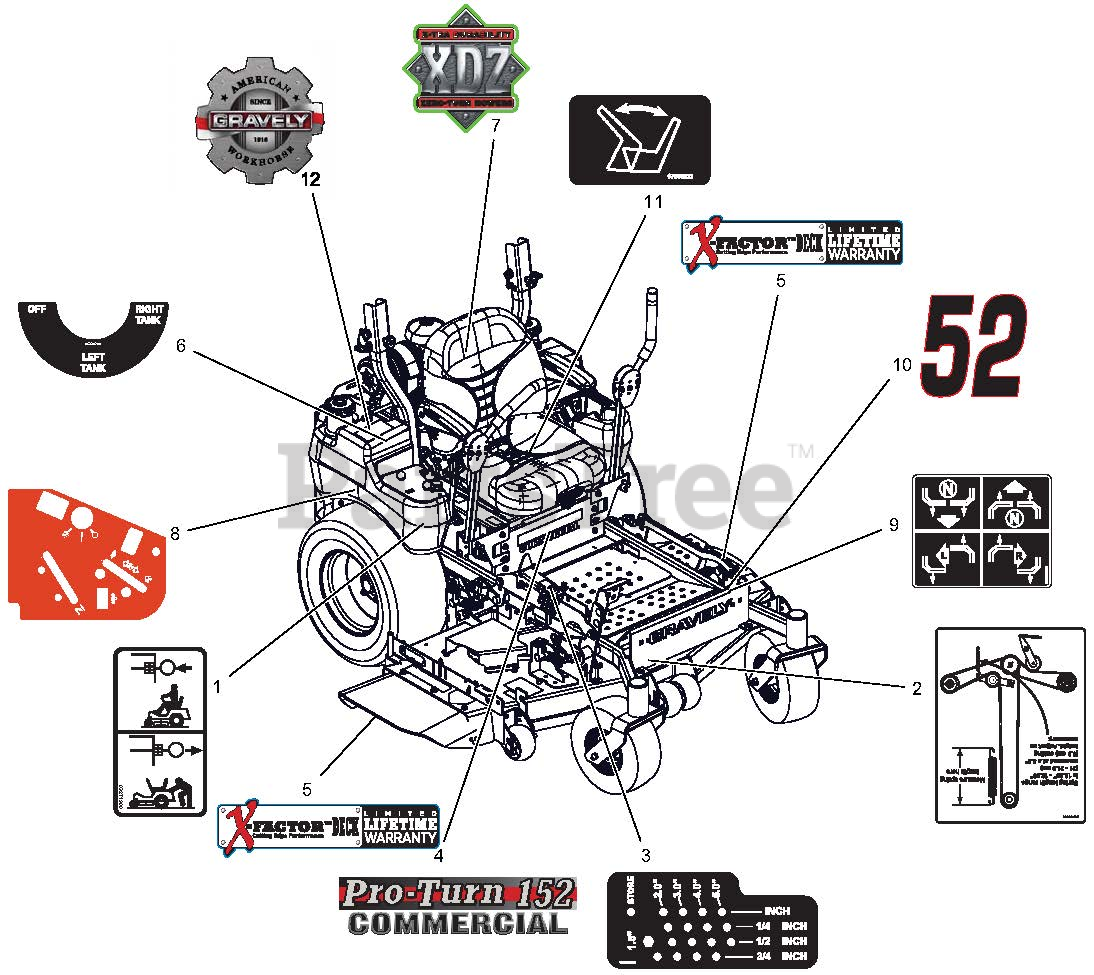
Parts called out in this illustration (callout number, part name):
1	DECAL, TRANSMISSION DISCONNECT
2	DECAL, BELT ROUTING
3	DECAL, HEIGHT OF CUT
4	DECAL, PRO-TURN 152
5	DECAL, X-FACTOR DECK
6	DECAL, FUEL VALVE
7	DECAL, XDZ
8	PANEL, PT100 CONTROL
9	DECAL, INSTRUCTIONAL - STEERING
10	DECAL, 52"
11	DECAL, SEAT RELEASE
12	DECAL, GRAVELY HERITAGE-LARGE
